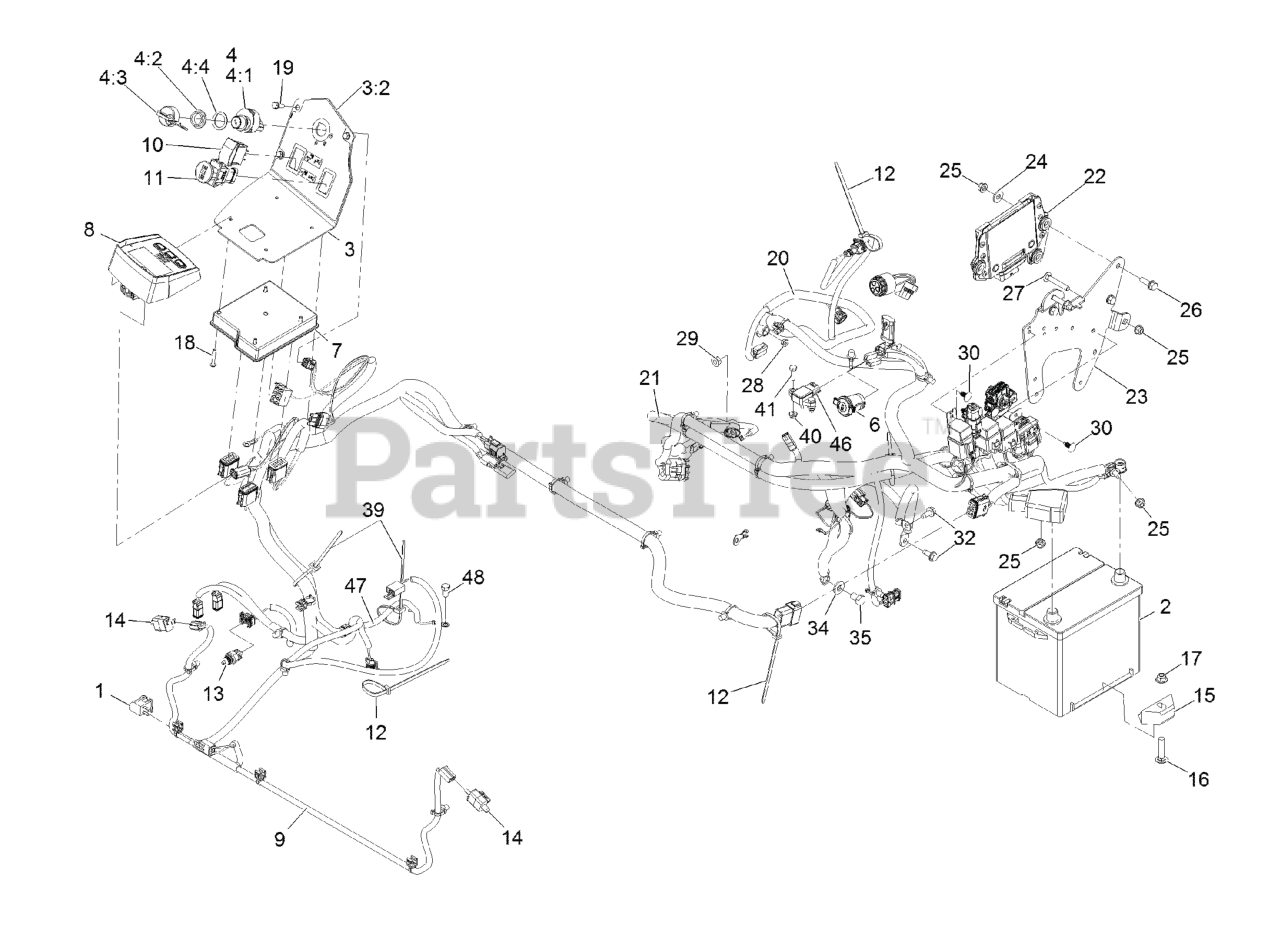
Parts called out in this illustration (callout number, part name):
1	SWITCH-BAIL
2	Battery-Dry
3	Console ASM
3:2	DECAL-CONTROL PANEL
4	IGNITION SWITCH ASM
4:1	Switch-Ignition
4:2	NUT-MOUNTING
4:3	IGNITION KEY SET
4:4	WASHER-BACKUP
6	PORT-POWER, 12V
7	Module-Mcu
8	MODULE, LDU
9	HARNESS-WIRE
11	SWITCH-PTO, SEALED
12	TIE-PLASTIC
13	SENSOR-TEMPERATURE
15	RETAINER-BATTERY
16	SCREW-CARR
17	NUT-HF, NI
18	SCREW-PPH
19	SCREW-HWH
20	HARNESS-WIRE
21	CABLE-BATTERY
22	ECU ASM
23	BRACKET-MOUNT, ECU
24	WASHER-FLAT
25	NUT-HF, NI
26	SCREW-HHF
27	BOLT-CARR
30	PLUG-PLASTIC
32	Screw-HWH 5/16-18 X 3/4 Tf
34	WASHER-BELLEVILLE
35	SCREW-HH
39	TIE-CABLE
41	SCREW-HH
46	SENSOR-ATM
47	HARNESS-WIRE, JUMPER
48	BOLT
